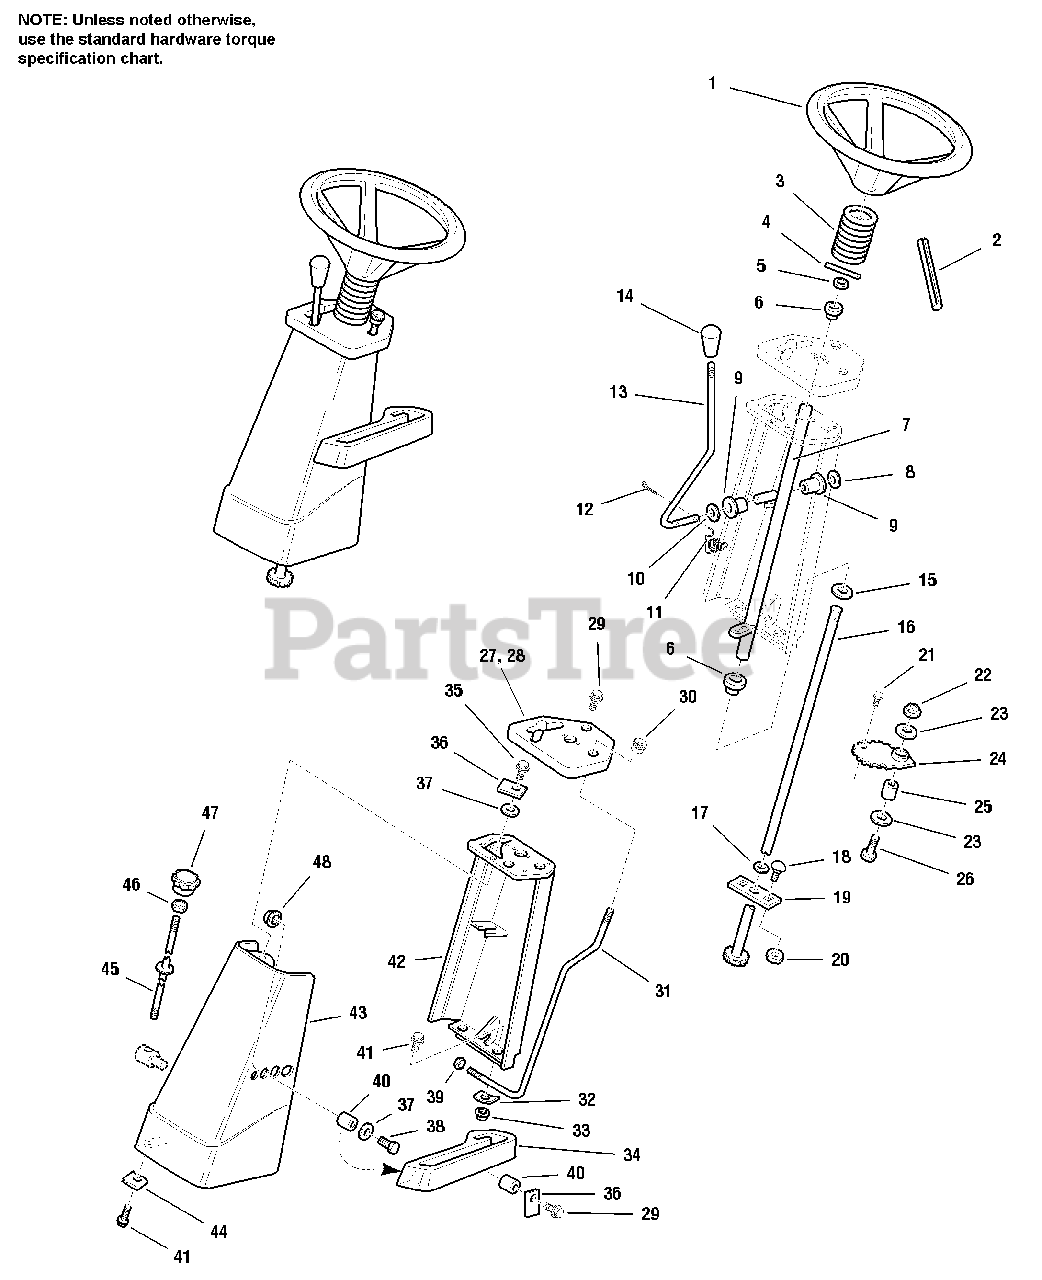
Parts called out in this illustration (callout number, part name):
1	STEERING WHEEL ASSY.
2	ROLL PIN, .188 x 1
3	TUBE, Steering
5	WASHER, Plain, 49/64 x 1-1/16 x 5/64
7	TUBE ASSY., Shift
8	WASHER, Plain
10	WASHER, Plain, 17/32 x 1-1/4 x 7/64
11	SPRING, Torsion
12	COTTER PIN
14	KNOB, Rod, Shift
15	WASHER, Plain, 11/32 x 1 x 1/8
16	SHAFT ASSY., Steering
17	WASHER, Plain
18	CARRIAGE BOLT, 3/8-16 x 1
19	PLATE, Steering Mounting
20	NUT, Hex, 3/8-16
21	CAPSCREW, Hex Hd., 5/16-18 x 1-1/2
22	NUT, Hex, Flange Lock, 3/8-16
23	WASHER, 13/32 x 1-1/2 x 1/8
24	GEAR, Steering
26	CAPSCREW, Hex Hd., 3/8-16 x 2
27	DASH, Hydro
29	SCREW, Hex, Flange, Taptite, 1/4-20 x 3/4
30	KNOB, Rod, Parking Brake
31	ROD, Parking Brake
32	PUSH NUT, 5/16
33	NUT, Hex, Flange, Whizlock, 5/16-18
34	QUADRANT, Lift
35	SCREW, Hex, Flange, Taptite, 1/4-20 x 1/2
37	WASHER, Plain, 1/4
38	CAPSCREW, Hex, 1/4-20 x 7/8
39	NUT, Hex, Flange, 1/4-20
40	SPACER, 17/64 x 3/8 x 21/64
41	SCREW, Hex, Whizlock, 5/16-18 x 3/4
42	SUPPORT, Steering
43	SHROUD, Front (Orange)
44	PAL NUT, 5/16-18
45	ROD, Lift Height
46	NUT, Hex, Jam, 1/4-20
47	KNOB, Rod, Lift Height
48	NUT, Hex, Flange, Whizlock, 1/4-20
